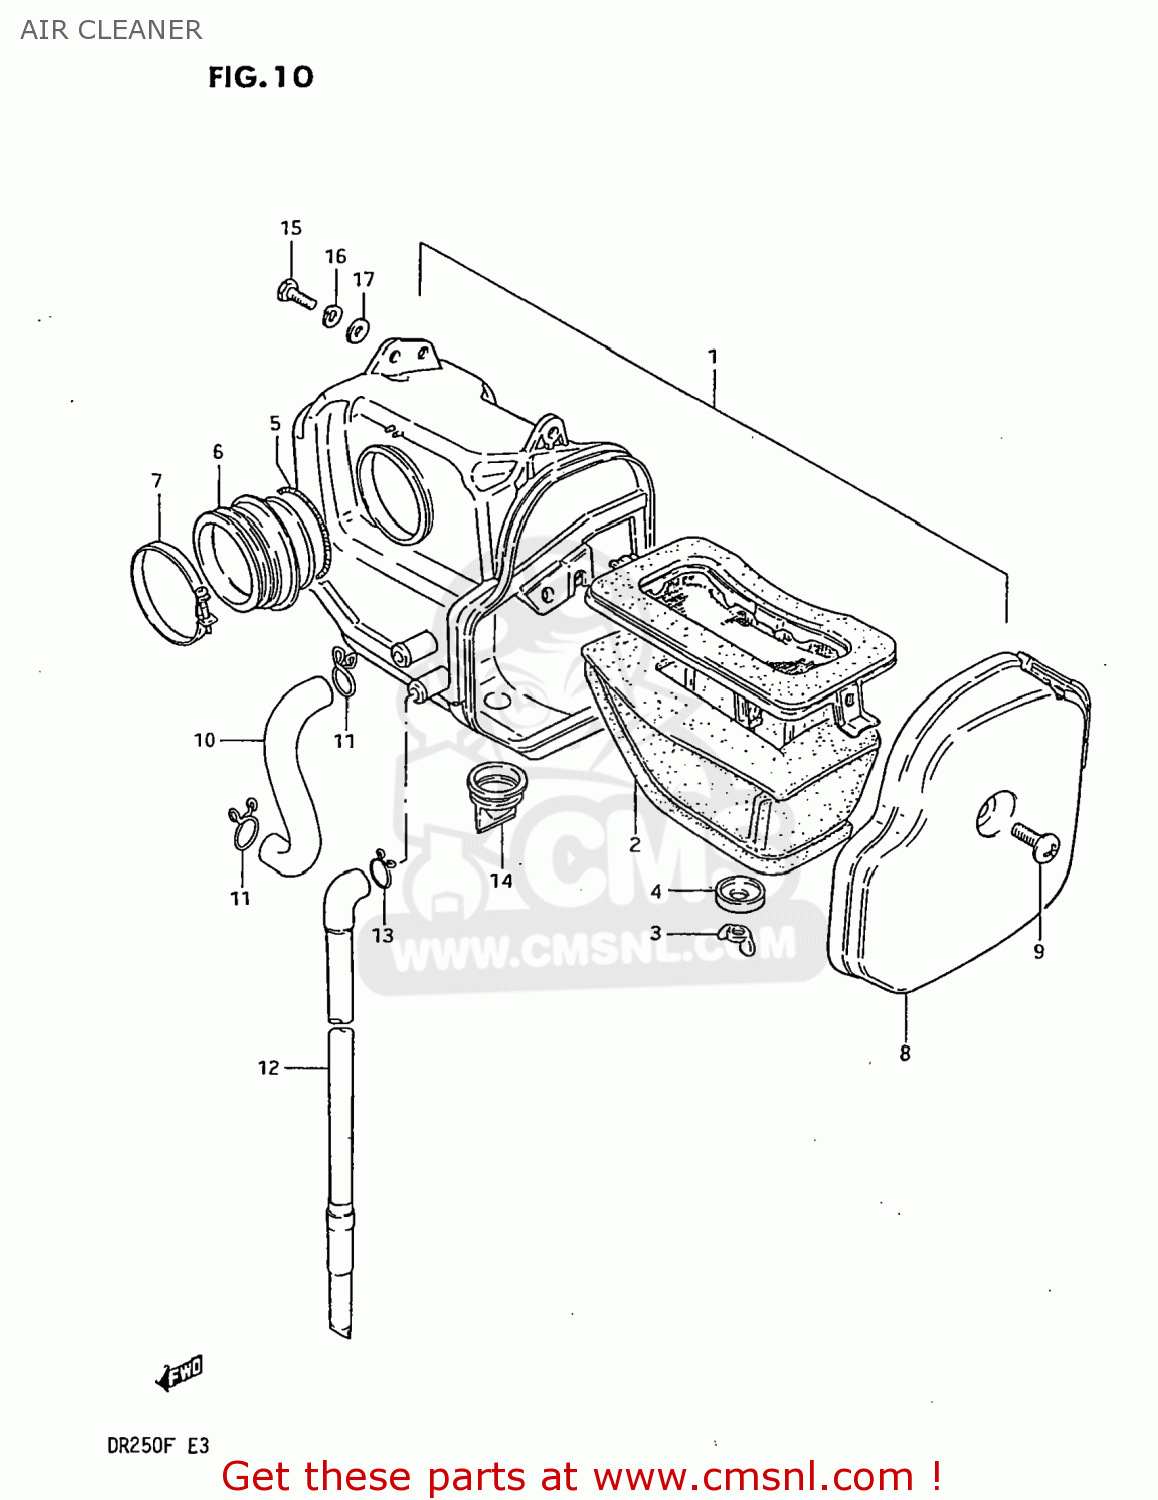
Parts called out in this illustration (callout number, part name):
1	CLEANER ASSEMBLY,AIR
2	ELEMENT,AIR CLEANER
3	NUT
4	WASHER
5	CLAMP,CLEANER SIDE
6	TUBE,AIR CLEANER OUTLET
7	CLAMP
8	CAP
9	SCREW
10	TUBE,BREATHER
11	CLAMP
12	DRAIN TUBE
13	CLIP
14	HOSE,AIR CLEANER DRAIN
15	BOLT, UPPER
16	LOCK WASHER
17	WASHER
